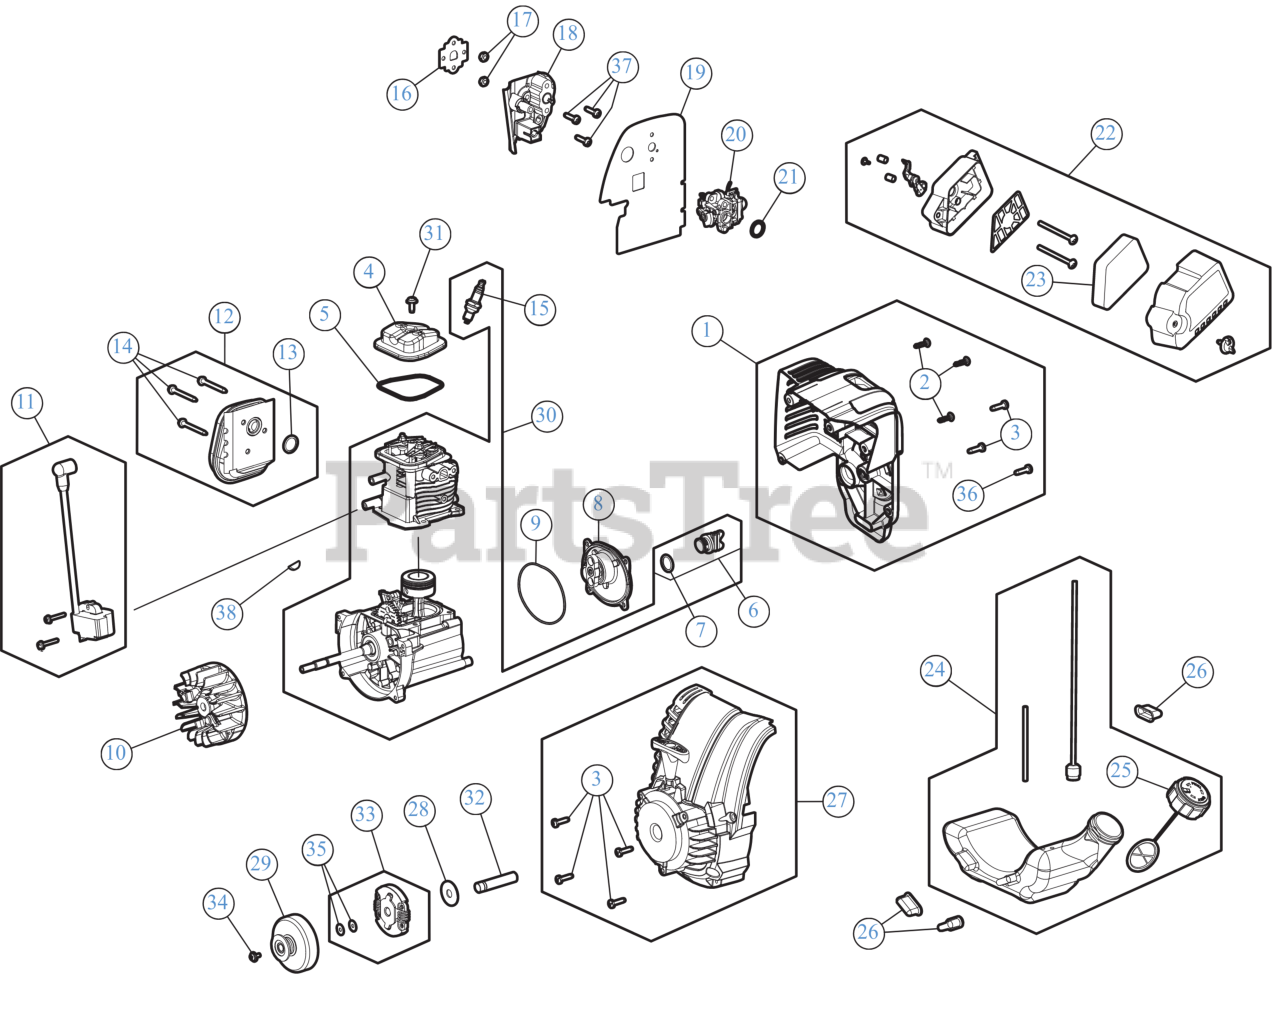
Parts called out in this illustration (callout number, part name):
1	REAR ENGINE CVR
2	SCREW 8-16 x 3/4
3	SCREW M5-0.8 x 19
4	ROCKER COVER
5	O-RING
6	OIL PLUG
7	RING, OIL PLUG (AC
8	CRANKCASE COVER
9	O-RING CRNKCSE CVR
10	FLYWHEEL ASSEMBLY AC3.1
11	MODULE ASSEMBLY
12	MUFFLER ASSEMBLY
13	GASKET/MUFFLER
14	SCREW M5 x 44MM
15	SPARK PLUG 4 CYCL
16	GASKET/INSULATOR
17	NUT 10-32
18	CARB INSULATOR
19	GASKET
20	CARBURETOR
22	AIR CLEANER COVER
23	AIR FILTER
24	FUEL TANK ASSEMBLY
25	FUEL CAP ASSEMBLY 43MM-6 W/O HOLE
26	FUEL TANK PADS
27	STARTER HOUSING (LIB RED)
28	WASH, CLUTCH O.D. 1.155 +/- .0
29	CLUTCH DRUM/PULLEY
30	SHORT BLOCK
31	SCR, VALVE COVER
32	SPACER :2.165"
33	CLUTCH WITH SPACER
34	SCREW 8-32X.375 PH S
35	WASH, NORAM CLUTCH
36	SCR, M5 x 15.8MM
37	SCREW, M5 X18
38	WOODRUFF KEY #403-.125 x .375
